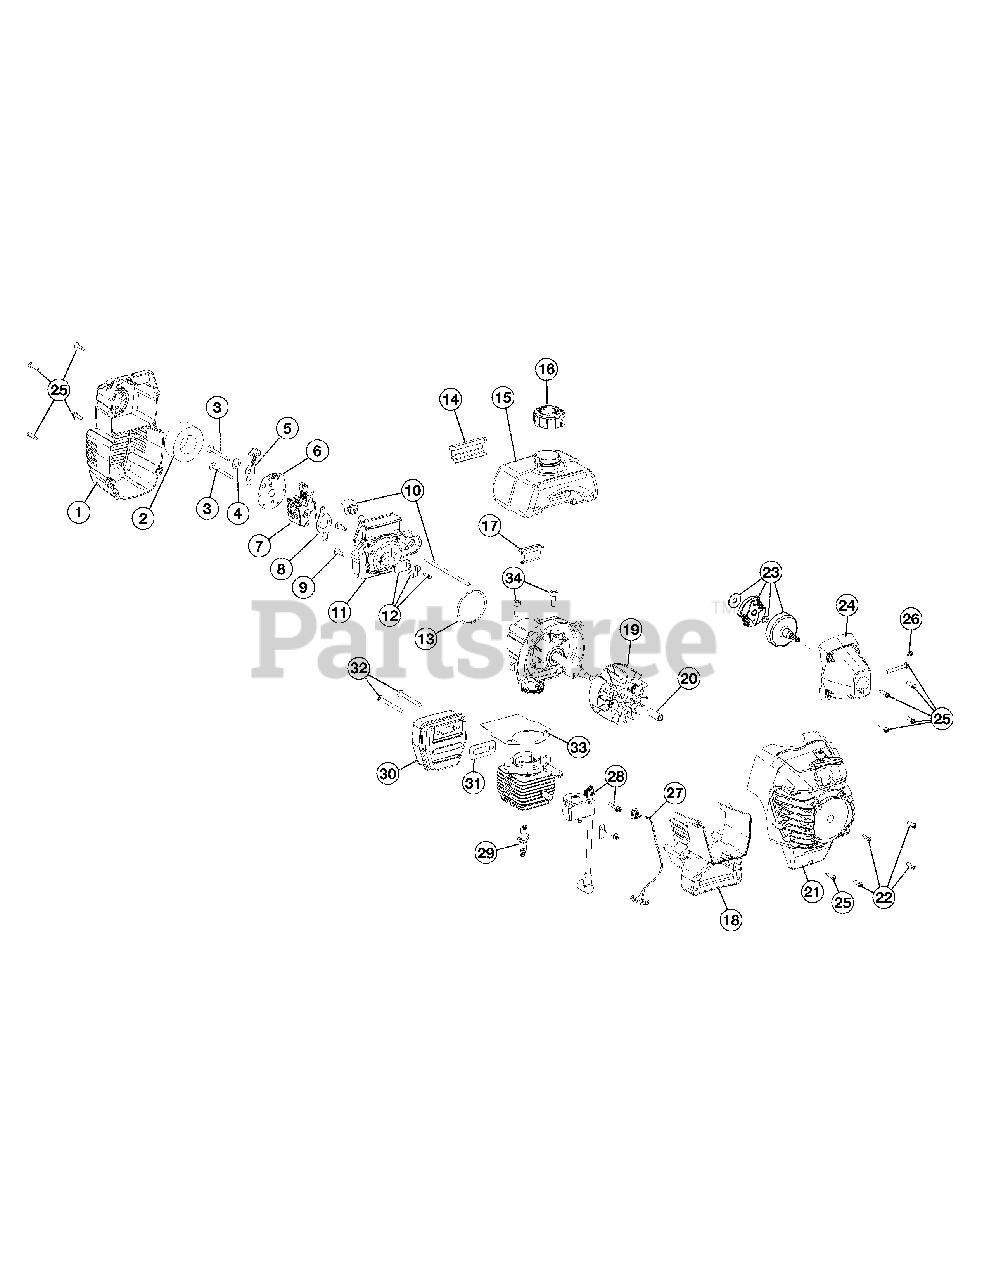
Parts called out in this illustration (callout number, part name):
1	Air Cleaner Cover Assembly
2	Air Cleaner Filter
3	Carburetor Mounting Screw Assembly
4	Wavey Washer
5	Choke Lever Assembly
6	Choke Plate Assembly
7	Carburetor Assembly
8	Carburetor Gasket
9	Carb Mount Screw
10	Primer & Hose Assembly
11	Carb Mount Assembly
12	Reed Assembly
13	Carburetor O-Ring
14	Rear Mounting Pad
15	Fuel Tank Assembly
16	Fuel Cap Assembly
17	Front Mounting Pad
18	Shroud Extension & Stand
19	Flywheel Assembly
21	Starter Housing Assembly
22	Housing Screw
23	Clutch Rotor Assembly
24	Clutch Cover Assembly
25	Cover Screw
26	Anti-Rotation Screw
27	Wire Leads and Sleeve
28	Module Assembly
29	Spark Plug
30	Muffler Assembly
31	Exhaust Gasket
32	Muffler Mounting Bolts
33	Cylinder Gasket
34	Cylinder Bolt
